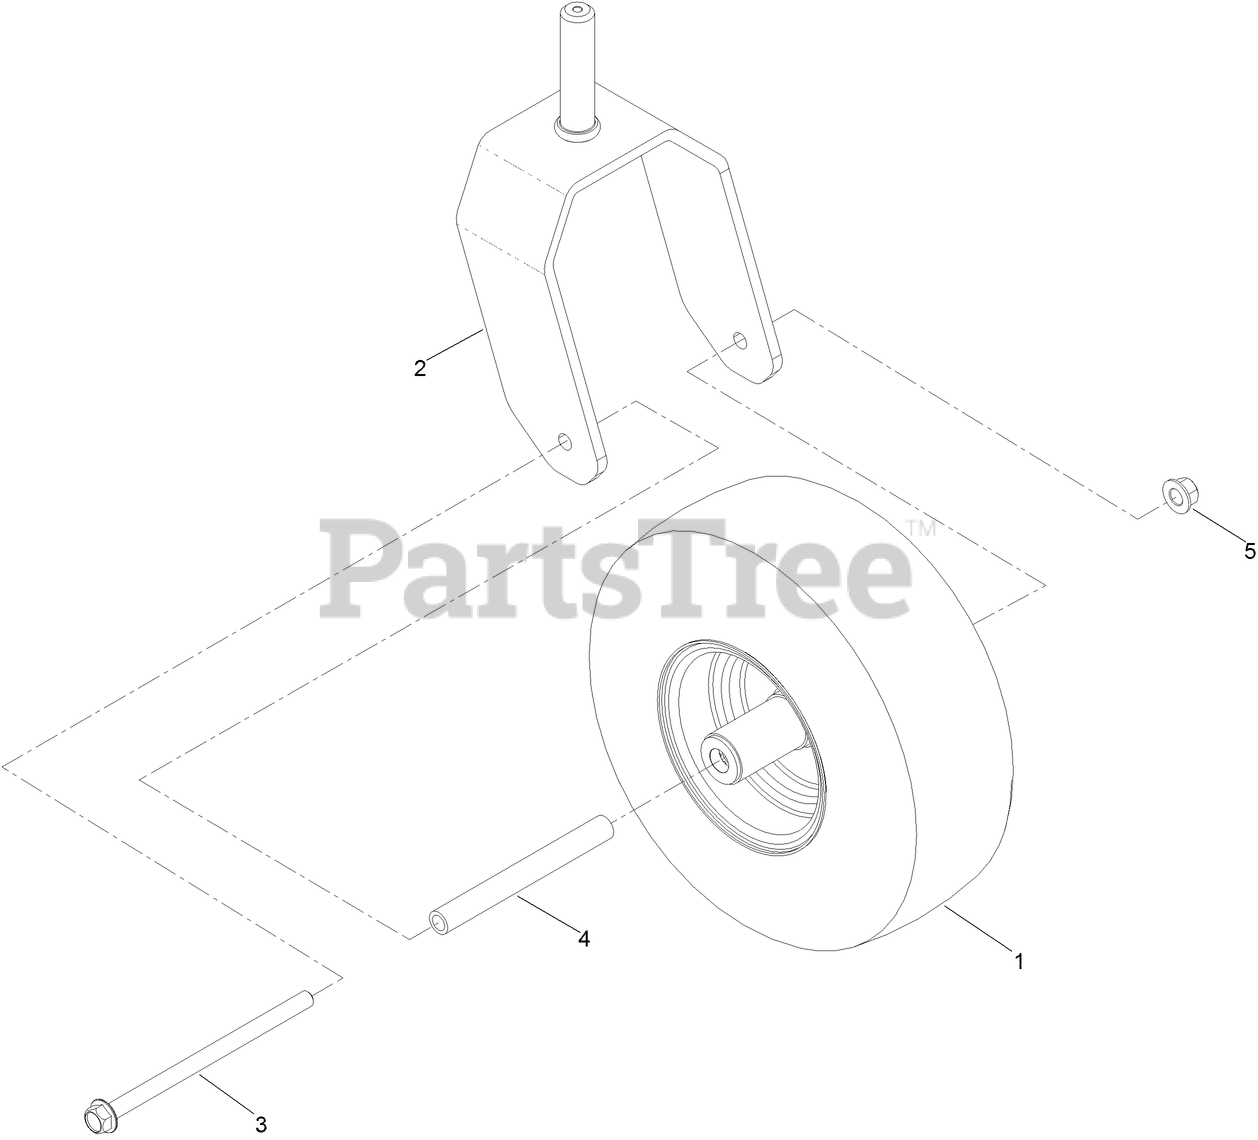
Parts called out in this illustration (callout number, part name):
1	WHEEL AND TIRE ASM
2	FORK-CASTER
3	SCREW-HHF
4	SPANNER-WHEEL, CASTER
5	NUT-LOCK
